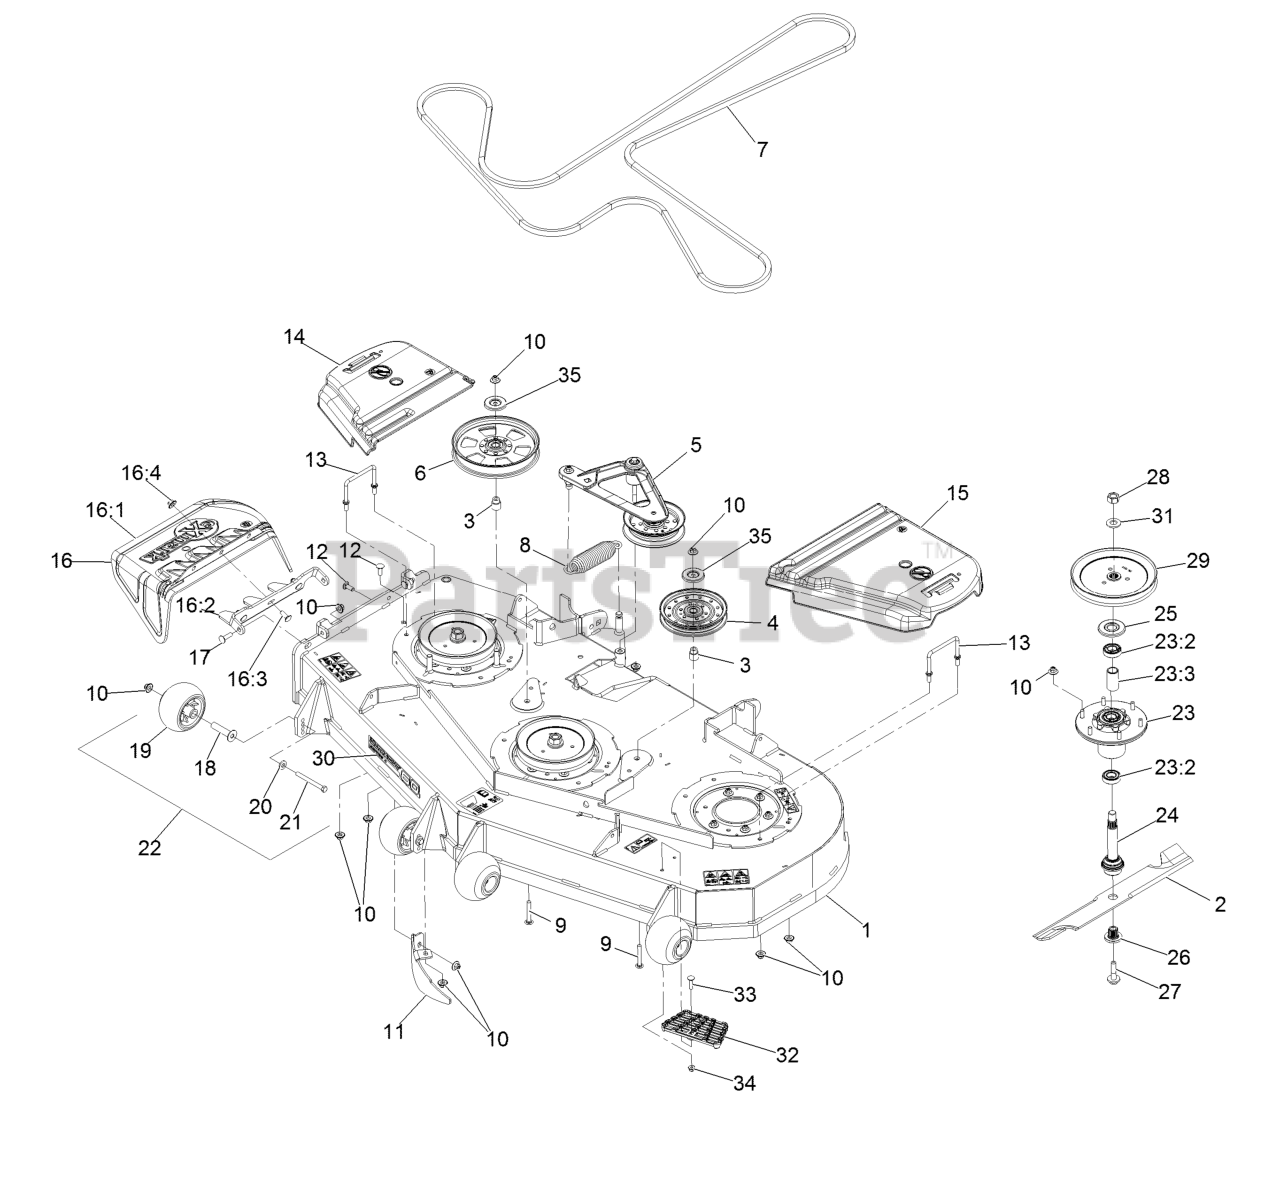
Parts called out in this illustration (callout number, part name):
1	Deck ASM,W/Decals 60
2	Blade, Solid
2	Blade, Low Lift
2	Blade, Mulching
2	Blade, Notched
2	Blade-Extreme 2, 20.50"
3	Bushing, Idler
4	Idler-Pulley
5	Deck Idler ASM
6	Pulley-Idler, Flat
7	Belt,V-5V-198.75
8	Spring-Extension
9	Bolt-Carriage 3/8-16 X 2 1/2
10	Nut-Nyloc 3/8-16 Flg
11	Dogleg - Lz60
12	Bolt-Carriage 3/8-16 X 1
13	Wireform-Cover
14	Cover-Belt, RH
15	Cover-Belt, LH
16	ASM,Discharge Chute
16:1	Chute, Discharge
16:2	Bracket,Discharge Chute
16:3	Bolt-Carriage 3/8-16 X 1
16:4	Nut-Nyloc 3/8-16 Flg
17	Bolt-Carriage 3/8-16 X 1 1/4
18	Axle, Roller
19	Roller-Anti-Scalp
20	Washer-Spring Disc 3/8
21	Screw-HH 3/8-16 X 3 3/4 GR 8
22	Kit, Anti-Scalp Roller
23	ASM-Cutter Hsg With Bearings
23:2	Bearing-Ball
23:3	Spacer-Bearing
24	ASM-Spindle And Seal
25	Guard,Bearing Top .989
26	Bushing, Splined
27	Screw-Sems 1/2-20 X 2.19
28	Nut-Hex
29	Sheave,Blade Drive 7.25
30	Decal, 604
31	Washer-Spring Disc 3/4
32	Step-Deck
33	Bolt-Carriage 5/16-18 X 1 1/4
34	Nut-Nyloc 5/16-18 Flg
35	Shield-Dust
